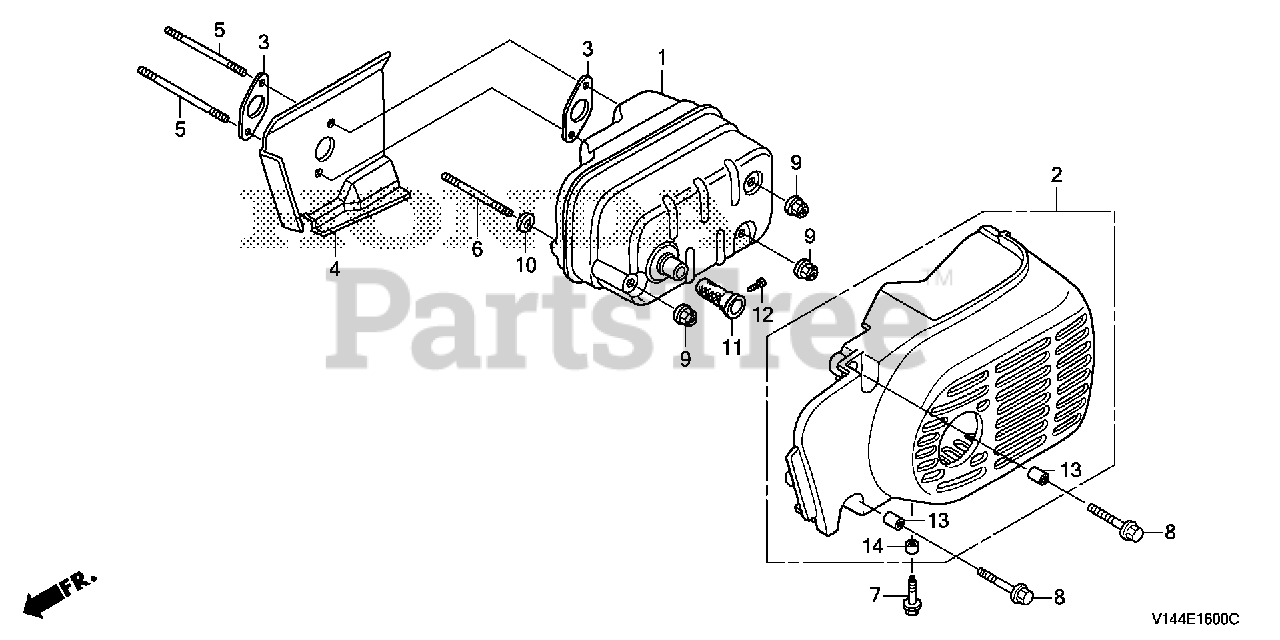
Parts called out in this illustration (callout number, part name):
1	MUFFLER
2	PROTECTOR, MUFFLER
3	GASKET, MUFFLER
4	GUIDE, AIR
5	BOLT 2, STUD (5X57)
6	BOLT 2, STUD (5X37)
7	BOLT, FLANGE (5X16)
8	BOLT, FLANGE (5X25) (CT200)
9	NUT, SELF-LOCK (5MM)
10	WASHER, STOPPER (14MM)
11	ARRESTER, SPARK
12	SCREW, TAPPING (4X8)
13	COLLAR, TAILLIGHT MOUNT
14	COLLAR, TOP COVER
